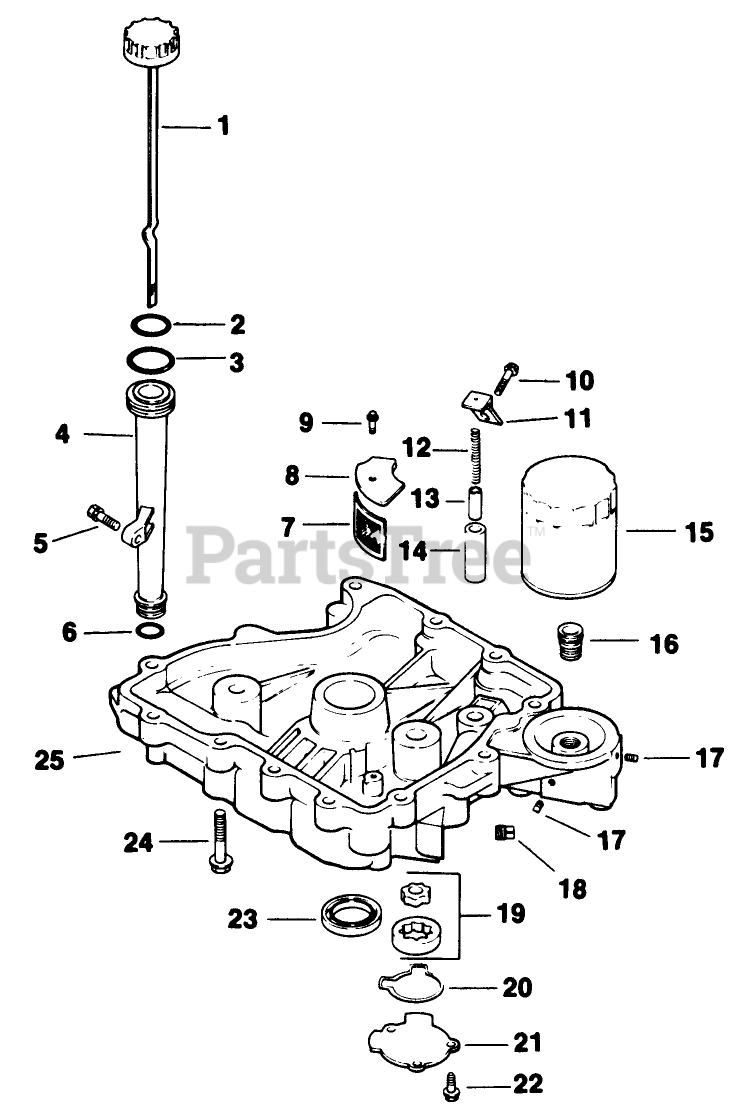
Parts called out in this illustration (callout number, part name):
1	Dipstick INC 2-3 (Only On: 72042, 72063, 72062, 72043)
2	ORing
3	O Ring-Upper Fill Tube (Only On: 72103)
4	Tube-Oil Fill
6	O-Ring-Lower Fill Tube (Only On: 72042, 72063, 72062, 72043)
7	Screen-Oil Pickup (Only On: 72042, 72063, 72062, 72043)
8	Cover-Oil Pickup Screen (Only On: 72042, 72063, 72062, 72043)
11	Bracket-Oil Pump Relief (Only On: 72042,72043,72062,72063)
12	Spring-Oil Relief Valve (Only On: 72042,72043,72062,72063)
13	Piston-Oil Relief Valve (Only On: 72042, 72063, 72062, 72043)
14	Body-Oil Relief Valve (Only On: 72042, 72063, 72062, 72043)
15	Filter-Oil
16	Adapter-Oil Filler
17	Plug-SH 1/8
19	Pump-Oil (Only On: 72042, 72063, 72062, 72043)
20	O Ring-Oil Pump Cover (Only On: 72042,72043,72062,72063)
21	Cover-Oil Pump (Only On: 72042,72043,72062,72063)
23	Seal-Crankshaft (Only On: 72042, 72043, 72062, 72063)
25	Pan-Oil
